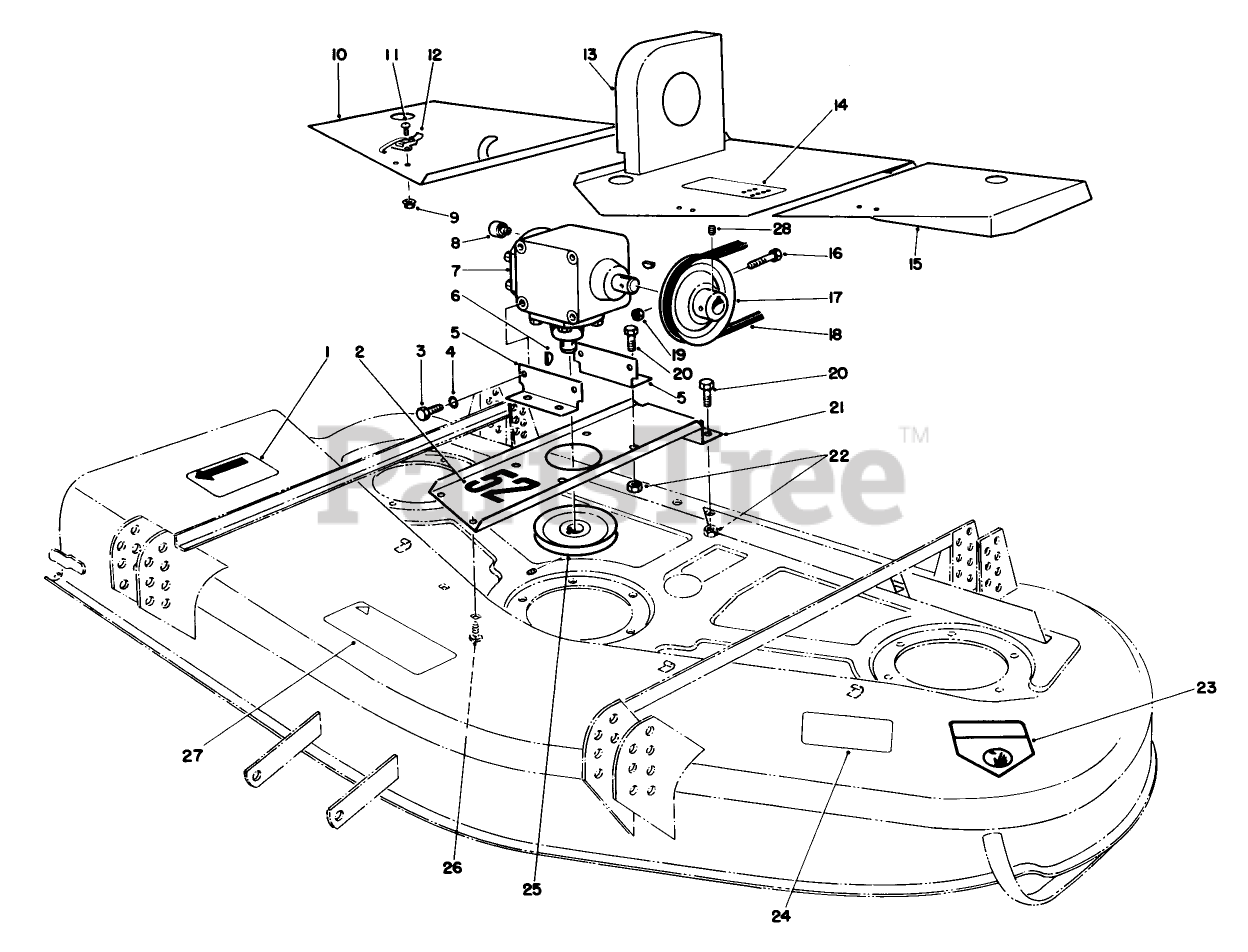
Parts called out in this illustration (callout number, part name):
2	DECAL
3	SCREW-HH
4	WASHER-LOCK
8	FITTING-LUBE
9	NUT-LOCK, FLANGE
11	SCREW-HWH
12	CLAMP-SLOTTED
16	SCREW-HH
17	PULLEY
18	V-BELT, DECK
19	NUT-LOCK, NI
20	SCREW-HH
22	NUT-LOCK, NI
23	DECAL-DANGER
25	PULLEY
26	BOLT-CARR
28	SCREW-HH
